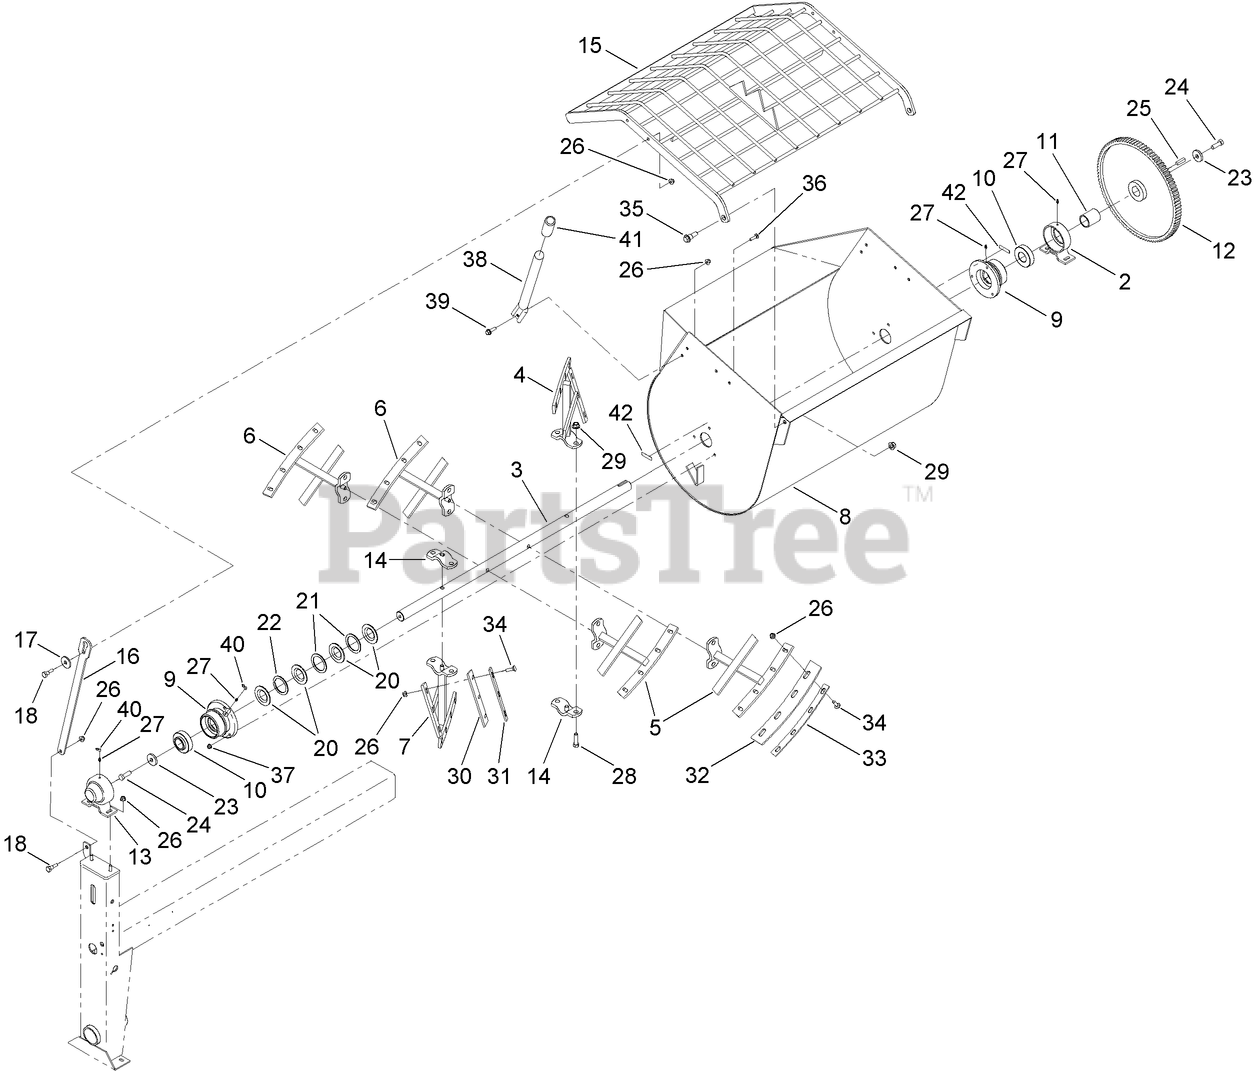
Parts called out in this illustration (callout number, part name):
2	TRUNNION
3	SHAFT-DRUM
9	HOUSING-BEARING
10	BEARING-BALL
11	SPACER-SHAFT, DRUM
12	GEAR-94 TEETH
13	TRUNNION-CAPPED
15	GUARD-DRUM
16	BAR-GUARD, LIFT
17	Washer-Thrust
18	BOLT-SHOULDER
20	SEAL-DRUM
21	WASHER-FLAT
22	WASHER-SPLIT
23	WASHER-FLAT
24	SCREW-HH
25	KEY-SQUARE
26	NUT-HF, NI
27	FITTING-GREASE
28	SCREW-HH
29	NUT-LOCK
30	BLADE-RUBBER, SHORT
31	BAR-BACKER, SHORT
32	BLADE-RUBBER, LONG
33	BAR-BACKER, LONG
34	BOLT-CARR
35	SCREW-SHOULDER, HHF
36	SCREW-CARR
37	NUT-HF, NI
38	HANDLE-DUMP
39	SCREW-HHF
40	CAP-PLUG
41	GRIP-HAND
42	DECAL-GREASE
